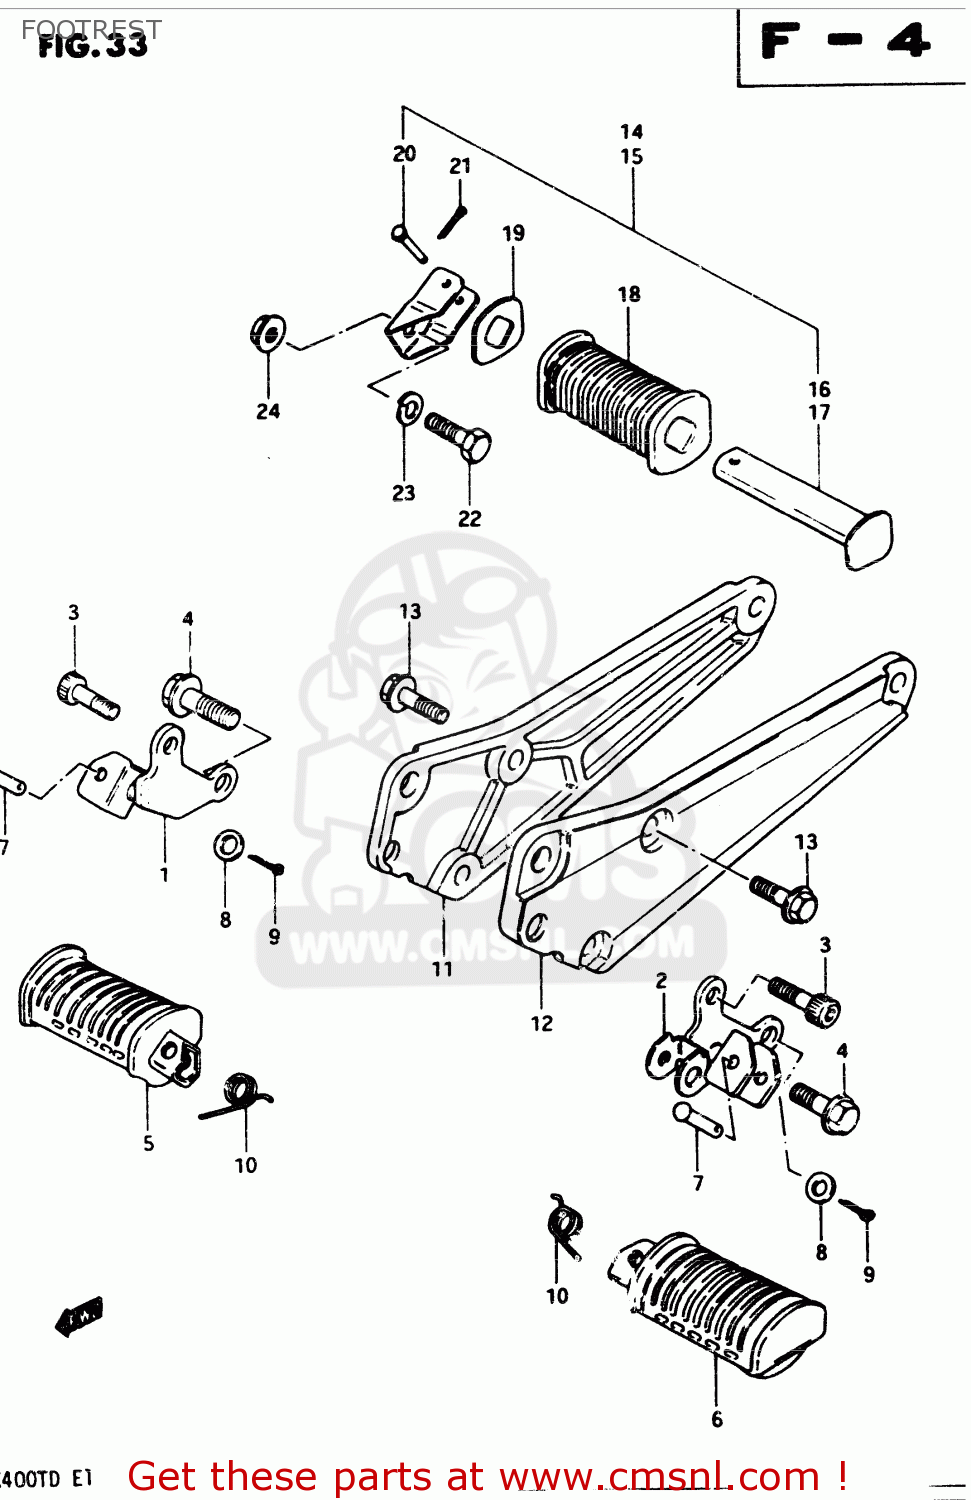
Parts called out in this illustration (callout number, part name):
1	BAR, FOOTREST RH
2	BAR, FOOTREST LH
3	BOLT
4	BOLT
5	RUBBER,PILLION FOOTREST,R
6	RUBBER,PILLION FOOTREST,L
7	PIN
8	WASHER
9	PIN 20X20
10	SPRING
11	BRACKET,MUFFLER,RIGHT
12	BRACKET,MUFFLER,LEFT
13	BOLT
14	FOOTREST ASSY,PILLION,R
15	FOOTREST ASSY,PILLION,L
16	BAR,REAR FOOTREST,RIGHT
17	BAR,REAR FOOTREST,LEFT
18	RUBBER,PILLION FOOTREST
19	WASHER,FOOTREST RUBBER
20	PIN
21	PIN 20X20
22	BOLT,M10X1.25X
23	LOCK WASHER
24	NUT
